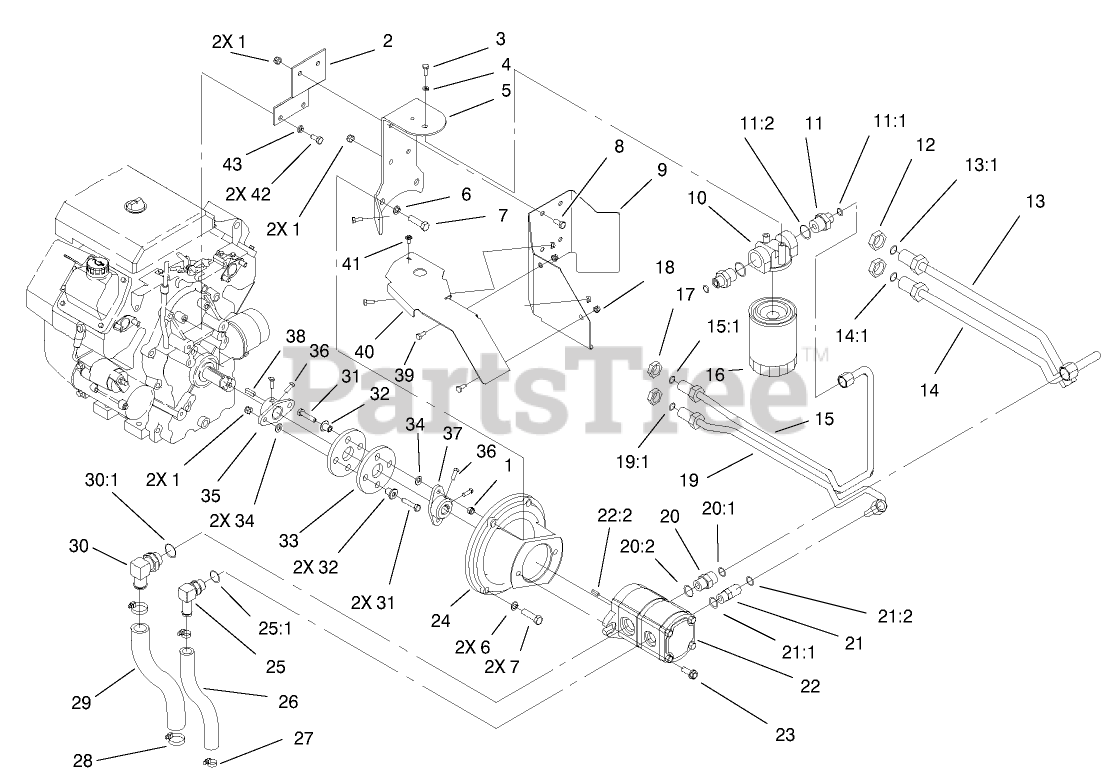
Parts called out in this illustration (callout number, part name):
1	NUT-LOCK, NI
2	BRACKET-SUPPORT, OIL FILTER
3	SCREW-HH
4	WASHER-LOCK
5	BRACKET-SUPPORT, OIL FILTER
6	WASHER-LOCK
7	SCREW-HH
8	SCREW-HH
9	SHIELD-HEAT, FILTER
10	HEAD-FILTER
11	FITTING-STR
11:1	O-RING
11:2	O-RING
12	NUT-LOCK, BULKHEAD
13	HYD TUBE ASM
13:1	O-RING
14	HYD TUBE ASM
14:1	O-RING
15	HYD TUBE ASM
15:1	O-RING
16	FILTER-OIL
17	NUT-BULKHEAD
18	NUT-LOCK, NI
19	HYD TUBE ASM
19:1	O-RING
20	FITTING-STRAIGHT
20:1	O-RING
20:2	O-RING
21	FITTING-ELBOW-90 DEG
21:1	O-RING
21:2	O-RING
22	PUMP-GEAR, HYD
22:2	KEY-SQUARE
23	SCREW-HHF
24	Mount-Pump
25	FITTING
25:1	O-RING
26	HOSE-HYD
27	CLAMP-HOSE
28	CLAMP-HOSE
29	HOSE-HYD
30	FITTING-HYD, 90 DEG
30:1	O-RING
31	SCREW-HH
32	SPACER
33	COUPLING-RUBBER
34	WASHER-PLAIN
35	HUB-ENGINE
36	SCREW-SQH
37	HUB-PUMP
38	KEY-SQUARE
39	SCREW-HH
40	SHIELD-HEAT
41	SCREW
42	SCREW-HH
43	WASHER-LOCK
